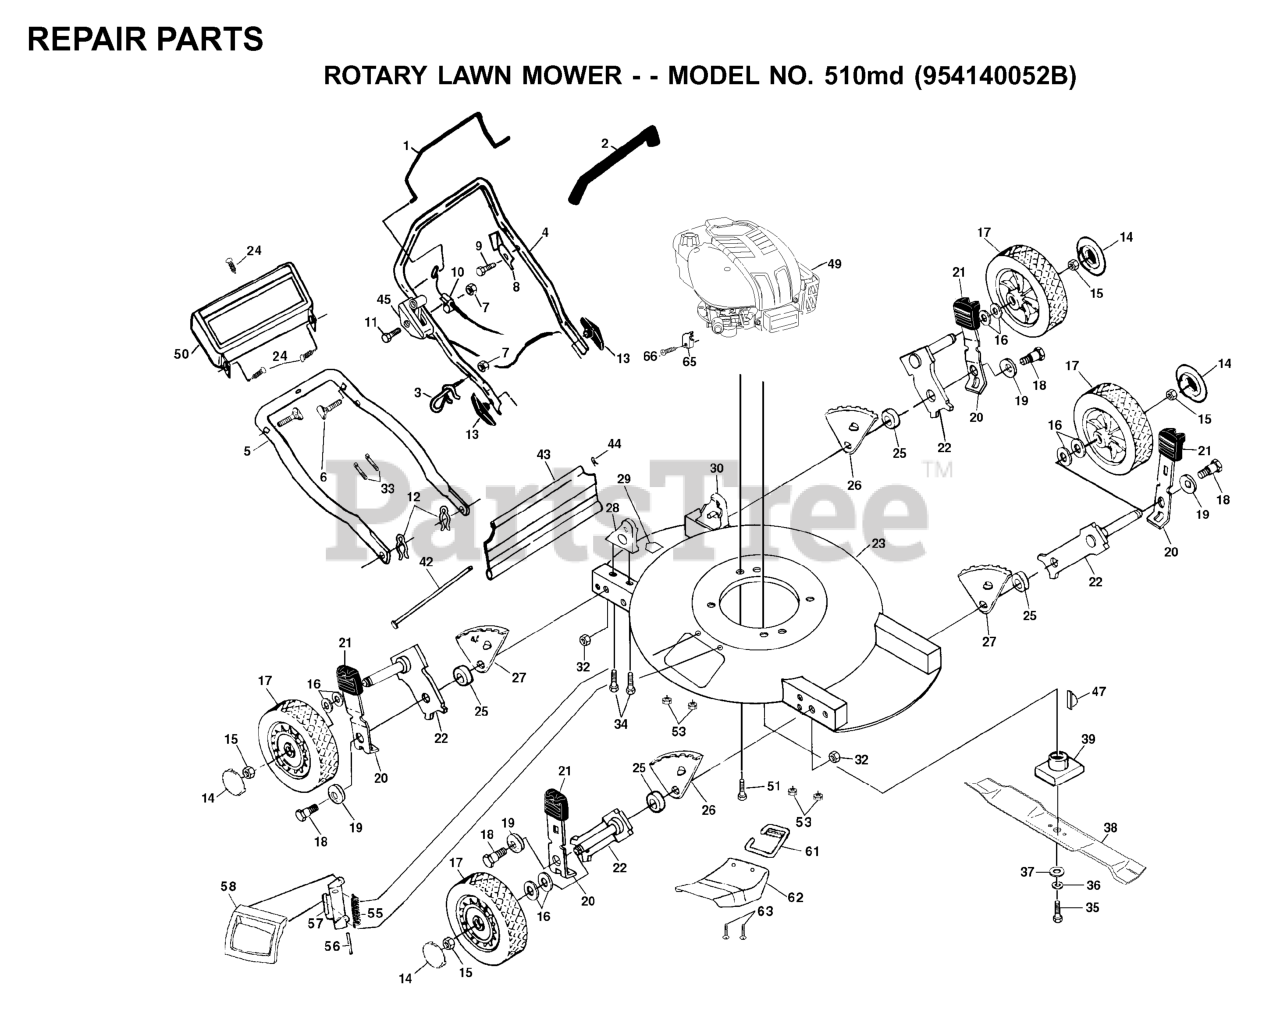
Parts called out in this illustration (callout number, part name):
1	CONTROL BAR/BLACK
2	GRIP.HANDLE.FOAM
3	ROPE GUIDE
5	HANDLE, LOWER
6	HANDLE BOLT
7	NUT
8	BRACKET UPSTOP
9	TAPPING SCREW
10	CABLE.CONTROL.MZR.RH.SP/PUSH
11	SCREW 1/4-20 X 2.12
12	HAIRPIN COTTER
13	HANDLE KNOB
14	HUB CAP PM
15	HEX FLANGE LOCKNT
16	WAVE WASHER
17	WHEEL & TIRE
18	BOLT
19	WASHER.BELLEVILLE (3 2 LB)
20	SELECTOR SPRING
21	SELECTOR KNOB
22	AXLE ARM
25	RP SPACER HT ADJ
26	WHL ADJ BRKT RF/LR
27	WHL ADJ BRKT LF/RR
28	HDLE BRKT ASSY RH
29	DECAL HYT
30	HDLE BRKT ASSY LH
32	LOCKNUT PM
33	TIE GUIDE
34	SCREW.5/16-18X3/4
35	SCREW, HEX HD 3/8-24 X 1-3/8
36	LOCKWASHER
37	WASHER,HARDEN
38	BLADE.20.MULCH.(50DK,6020MD)
39	BLADE ADAPTOR
44	RETAINER CLIP
45	THROTTLE CONTROL
50	TRIM PLATE
51	BOLT 3/8-16X1-1/8
53	NUT
55	TORSION SPRING
56	ROD.HINGE.COMBI-C
57	BRACKET PM
58	MULCHER DOOR
61	BRACKET.CHUTE.MTG
62	MULCHER DEFLECTOR
63	Truss Head Screw
65	WASHER
66	SCREW.HEX.HEAD.WASHER.10-16
